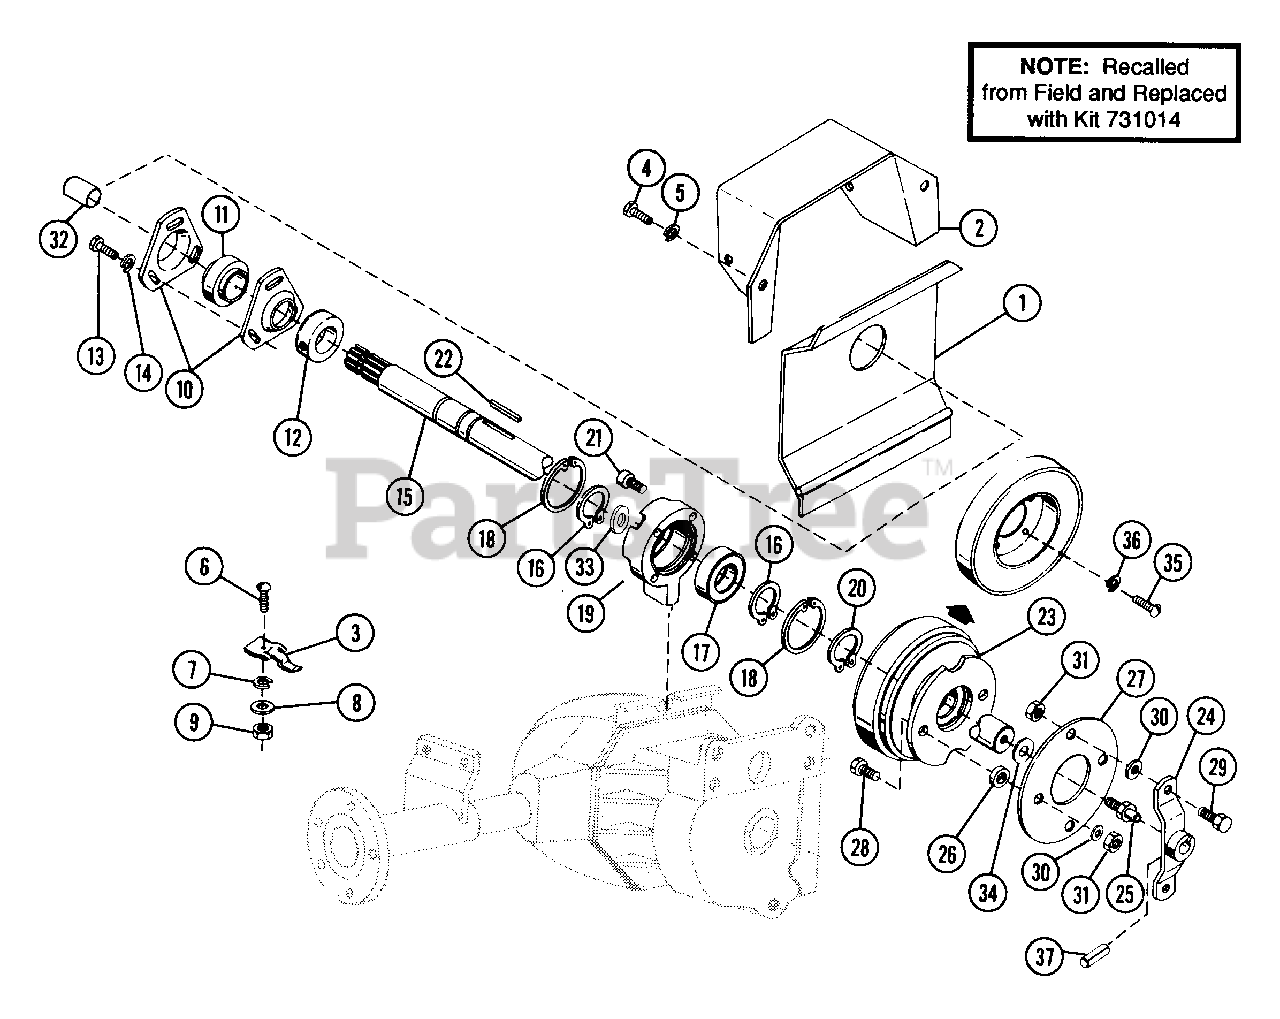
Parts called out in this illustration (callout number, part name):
1	REAR PTO COVER
2	PTO SHIELD
3	SNAP FASTENER
4	SCR-TAP .312-18X.75 HWH PL TR
5	WSHR-FL-STL .38X.875X.083 PL
6	SCR-MCH 10-24X1.00 SLRH PL
7	WSHR-LK-EXT #10 ID X .022
8	WSHR-FL-STL .219X.500X.049 PL
9	NUT-HEX 10-24 PL
10	BEARING FLANGE
11	BRG/W COLLAR 1.0 X 2.047 X.844
12	BEARING COLLAR
13	BLT-HEX .31-18X.75 PL GR2
14	WSHR-LK .312X.097 PL HVY
16	RG-RTNG-EXT 1.00X.042
17	BRG-BALL 1.0X2.0X.56
18	RG-RTNG INT 2.000X.062
19	BEARING MOUNT
20	RG-RTNG-EXT 1.00X.078
21	SCR-TAP 10-24X.375 HWH PL TR
22	KEY-SQ .25X1.0X.25 SAE 8630
23	ELECTRIC CLUTCH
24	COUPLING
25	STUD
26	SPACER .380X.750X.236
27	SPACER COUPLING
28	BLT-HEX .31-18X1.00 PL GR5
29	BLT-HEX .31-18X.75 PL GR5
30	WSHR-FL-STL.344X.688X.065PL
31	NUT-LK .312-18 GR A PL
32	SHAFT COVER
33	WSHR-FL-STL 1.015X1.500X.125
34	WSHR-FL-STL .390X1.500X.125
35	SCR-MCH 10-24X.62 SLRH PL
36	WSHR-LK 10X.047 MED PL
37	PIN-ROLL .250X1.25
